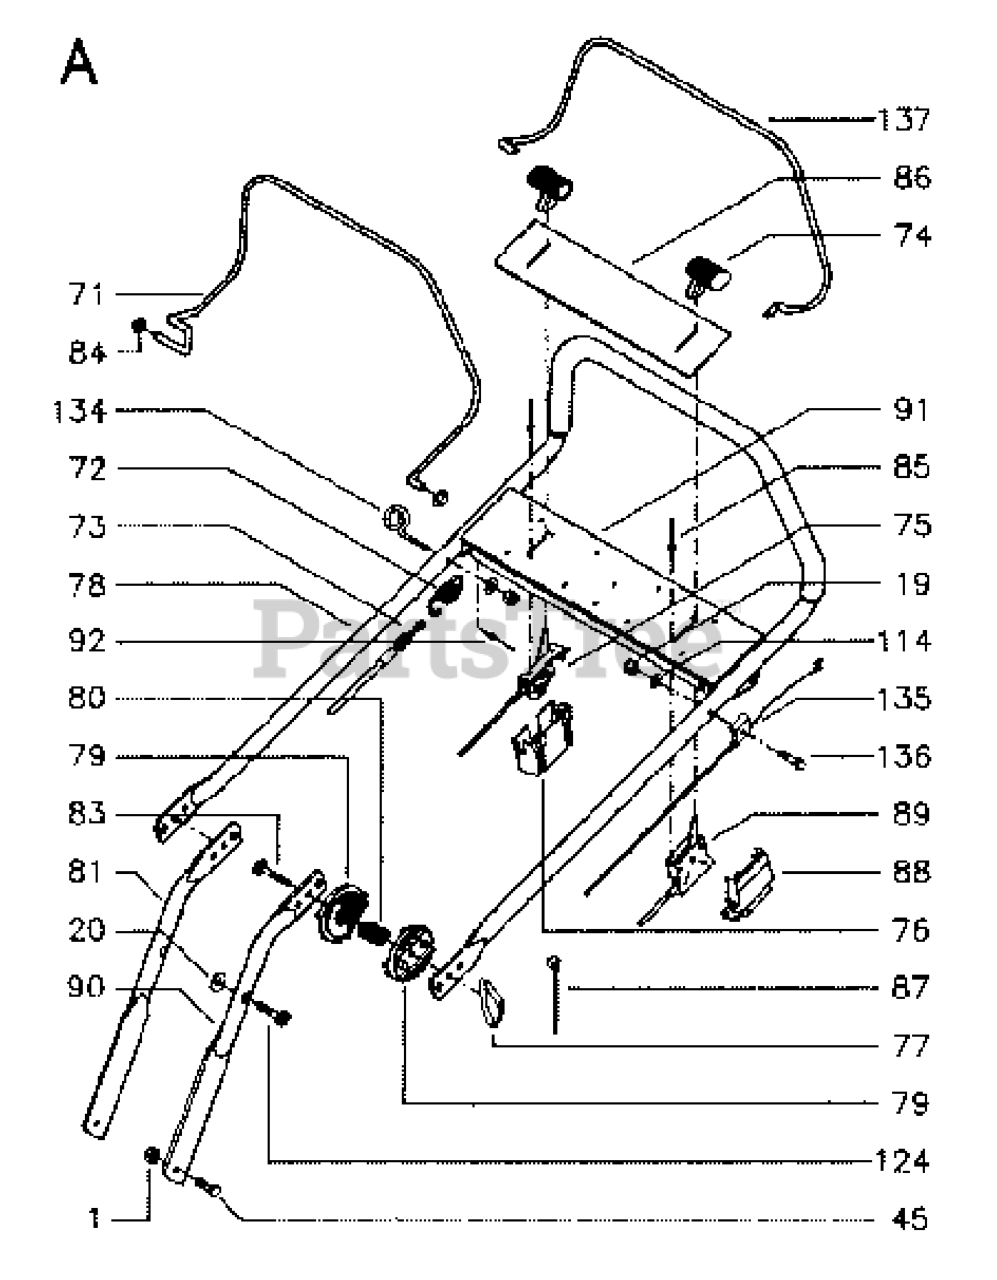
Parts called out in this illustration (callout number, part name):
3	APPLIQUE.SUBASM.GT.HUSQ.II
5	DASH.UPP.GT2.SM.PTO.MCHOKE
14	HOOD.ASM.HUSQVARNA.GT.TEX.ORAN
15	LENS.HEADLIGHT.LH.GTII.2011
18	GRILLE.SUBASM.GT.HUSQ.II
25	LENS.HEADLIGHT.RH.GTII.2011
34	PLATE.ENGINE.WELDED.CHASSIS
36	SCREW 5/16"
37	FENDER.PNT.TX.GT.CH/FW/DL.HUSQ
52	LOCKNUT
58	BRKT.SUPPORT.FNDR/TANK
68	Screw 5/16-18 x 1/2 Hex, Self Tapping 5/16-18 x 1/2
130	SCREW.#10 X 0.750.BOS
137	BUMPER DASH
150	AIR.DUCT.GTV.BLACK
151	BRACKET.PIVOT.HOOD.GT.HUSQ.II
152	SHIELD.BROWNING.W/TEX
161	CONSOLE.WINDOW.FUEL.HUSQ.GT
162	SCREW.HI-LO.CONSOLE
165	SUPPORT.TANK.REAR.W/TEX
175	PLATE.CROSSMEMBER.HUSQ
176	SCREW.#10-24X5/8.RN.QU
177	BUSHING, STEERING
180	CHASSIS.GT.SLOPED.DRAWBAR.
182	DASH.LOWER.COMMON.12V.ADAPTOR
183	BOLT.5/16-18X1-1/4 FULL THD
189	SCREW
191	INSERT.REFLECTIVE.RH.HUSQ.GTII
194	NUT LOCK HEX FLANGE 5/16-18
196	SUBASM.CONSOLE.HUSQ.GT.DECKLFT
199	PLATE.DECK.LIFT.HUSQVARNA.GT
202	VENT.SIDE.RH.GT.HUSQ.II.
203	VENT.SIDE.LH.GT.HUSQ.II.498
204	VENT.TOP.HUSQ.GT2
205	SIDE.TRIM.RH.GT.HUSQ.II
206	SIDE.TRIM.LH.GT.HUSQ.II.GRAY
207	BEZEL LIGHT.RH.GT.II.MYLAR
208	BEZEL LIGHT.LH.GT.II.MYLAR
213	BOLT
214	CLIP.RETAINER.TINNER.
217	ROD.PIVOT.HOOD
218	X-PIECE.HOOD.STOP.NON/
221	REFLECTOR.LH.TEX GT HU
228	STUD.FASTNER.W/ANTI-ROTATE
234	BUMPER.HOOD.TEX.HUSQVARNA
235	SPACER FENDER
236	NUT.CENTERLOCK.5/16-
289	PLUG.N/CRUISE.COMMON.YT/GT.BLK
297	INSERT.REFLECTIVE.LH.HUSQ.GTII
